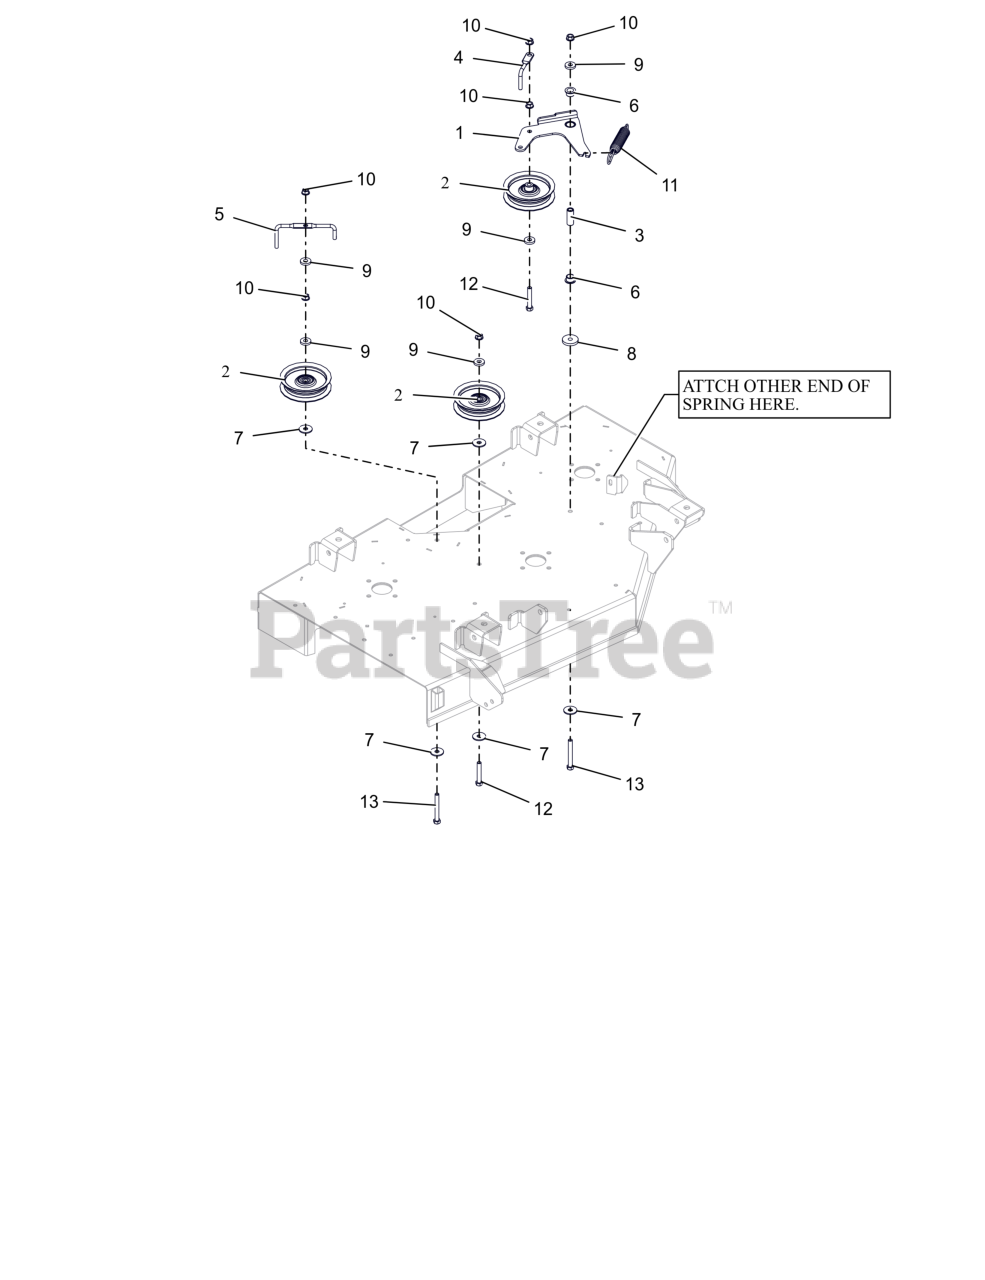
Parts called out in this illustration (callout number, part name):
1	WLDMT, IDLER ARM-42"
2	IDLER, FLAT - 4.06" X .75"
3	SPACER, .375IDX.625ODX1.66 PM
4	WIREFORM-BELT FINGER
5	BELT FINGER
6	BSHG-FLG, .625X.750X.500X1.00
7	WSHR FL STL .406X1.25X.10ZC120
8	WSHR, FLT .406X1.50X.245 ZCC
9	WSHR, FLT .406X1.00X.188 ZCC
10	NUT-LK-CTR-FLG .375-16 GF ZCC
11	SG-TENS .135X.98X6.0 WLD 62
12	BLT,HEX .38-16X2.25 G5 ZCC
13	BLT, HEX .38-16X3.00F G5 ZCC
